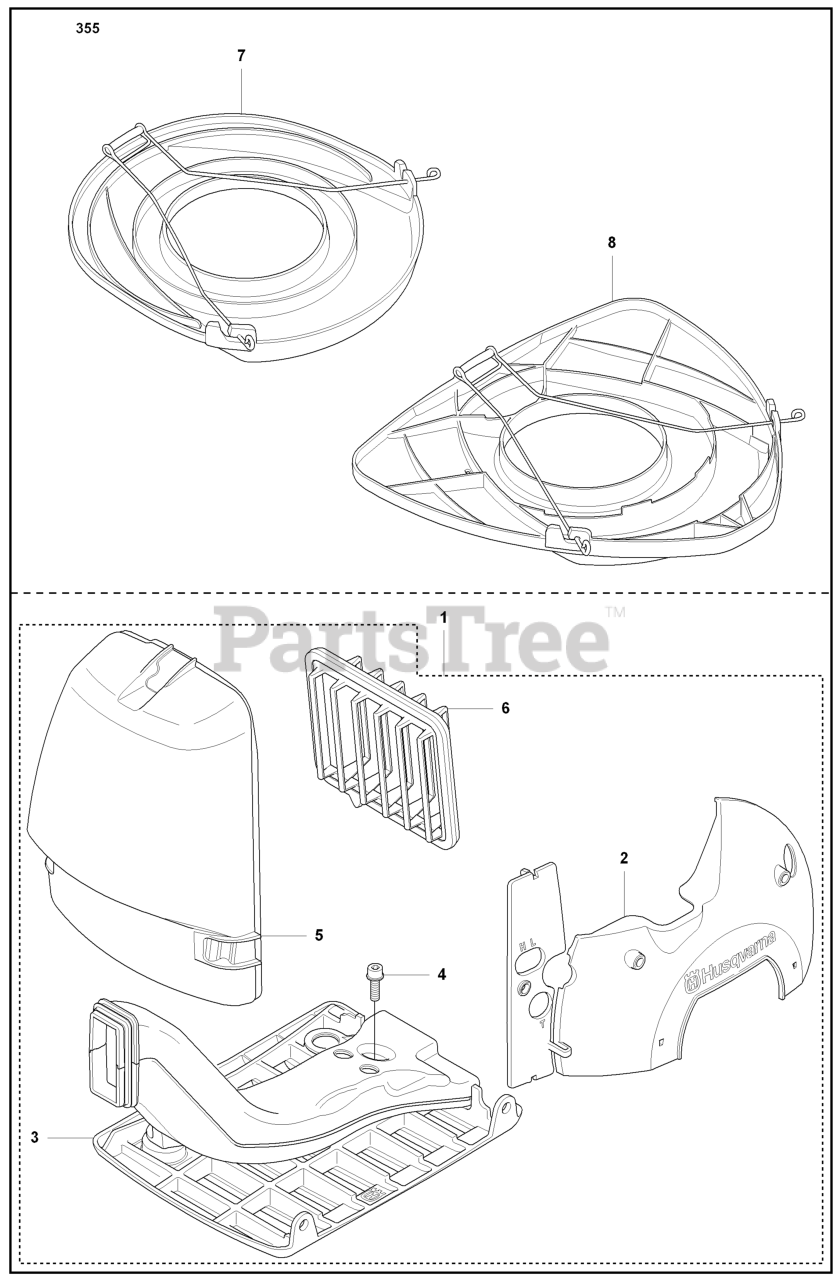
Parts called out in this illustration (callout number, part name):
1	WINTER KIT
2	WINTER COVER
6	FILTER
7	BLADE GUARD TRANSPORT
8	TRANSPORT GUARD
